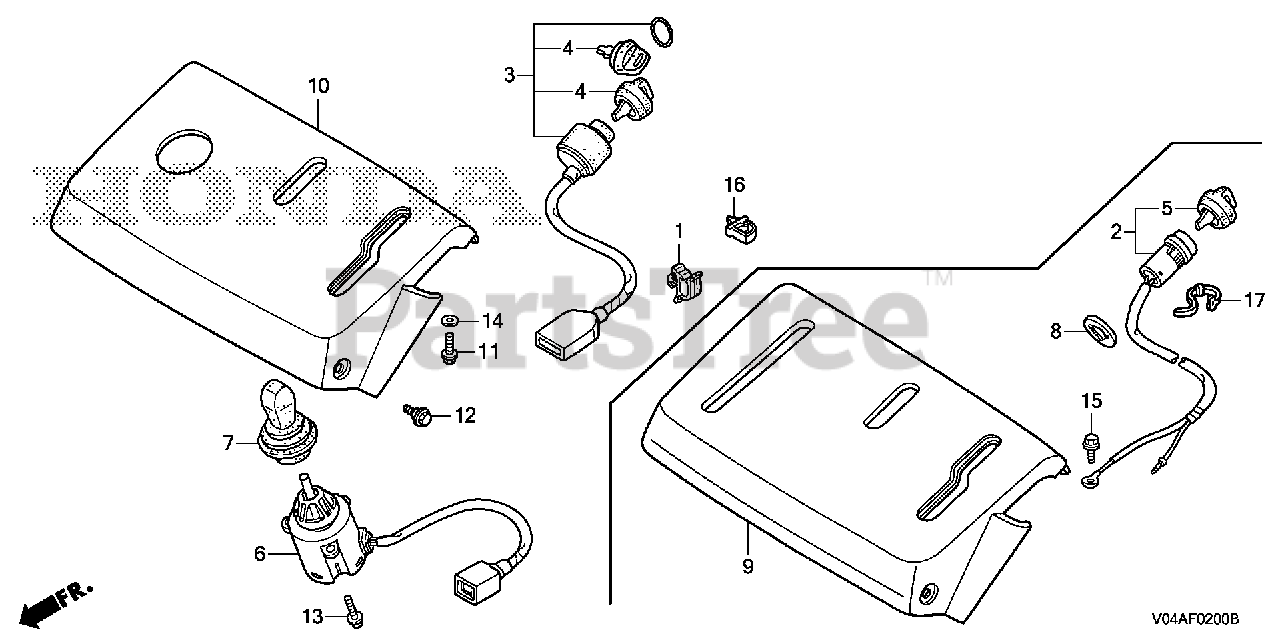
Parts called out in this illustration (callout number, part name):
2	SWITCH ASSY., COMBINATION
5	KEY ASSY., COMBINATION SWITCH (RED)
8	SPACER, ENGINE STOP SWITCH
9	PANEL, CONTROL *NH296* (ALPS GRAY)
11	BOLT, FLANGE (5X12)
12	BOLT, CONTROL PANEL
14	WASHER, PLAIN (5MM)
15	BOLT, FLANGE (6X10)
